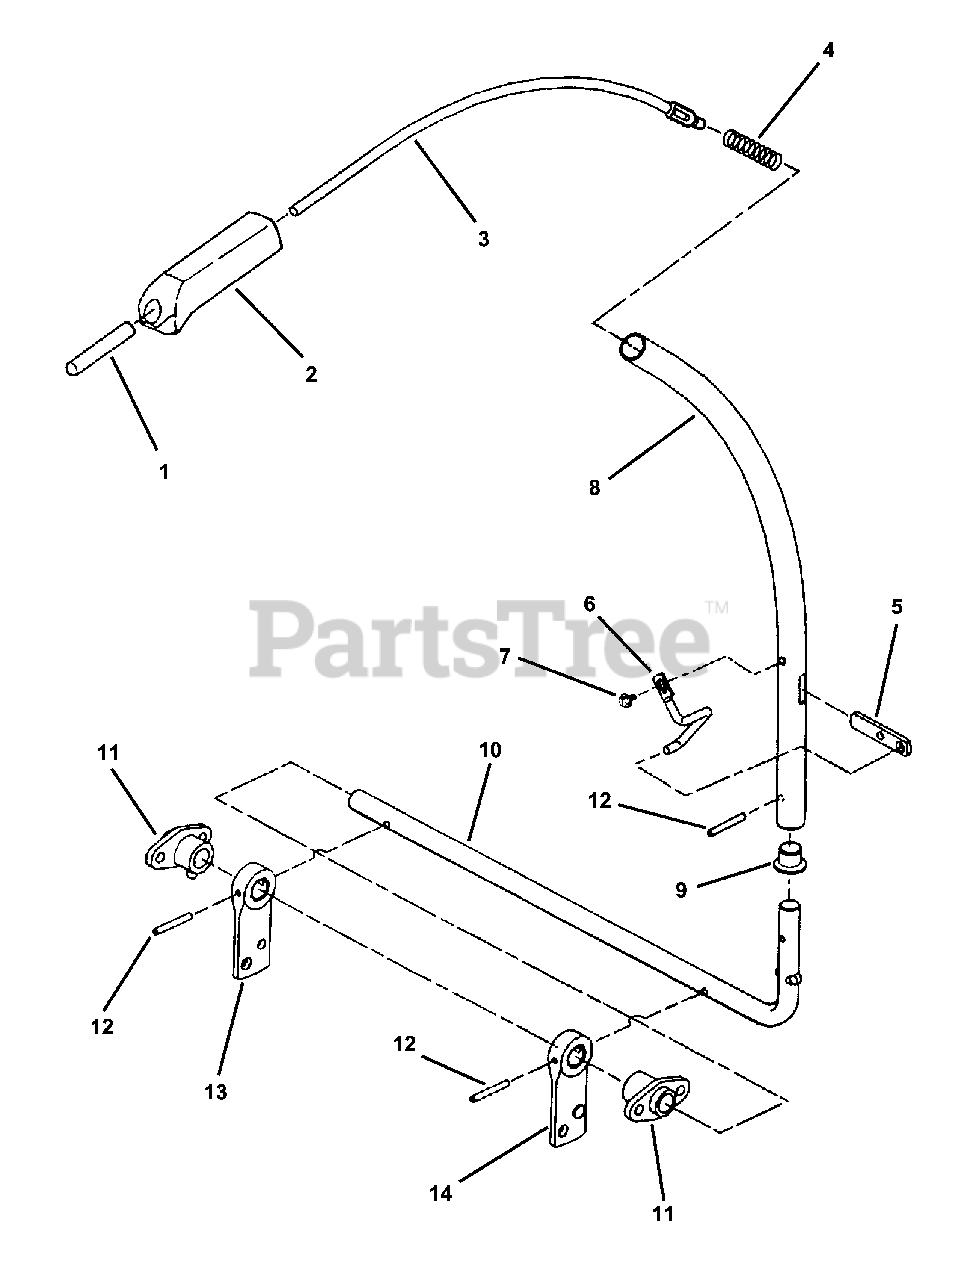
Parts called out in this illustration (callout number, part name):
1	GRIP, 5/16 x 2-1/2" Vinyl
2	GRIP, Brake/Clutch Handle
3	ROD, Park Brake
4	SPRING, Brake/Clutch Release
5	ARM, Brake/Clutch Lever
6	PIVOT, Brake/Clutch Lever
7	SCREW, 1/4-20 x 3/8" Slotted Hex Washer Head, Self-Tapping
8	TUBE, Brake/Clutch Lever
9	BUSHING, Nylon
10	ROD, Brake/Clutch
11	ASSEMBLY, Foot Shaft Pivot
12	ROLL-PIN, 3/16 x 1-1/2"
13	ARM, Brake/Clutch
14	ARM, Brake/Clutch
